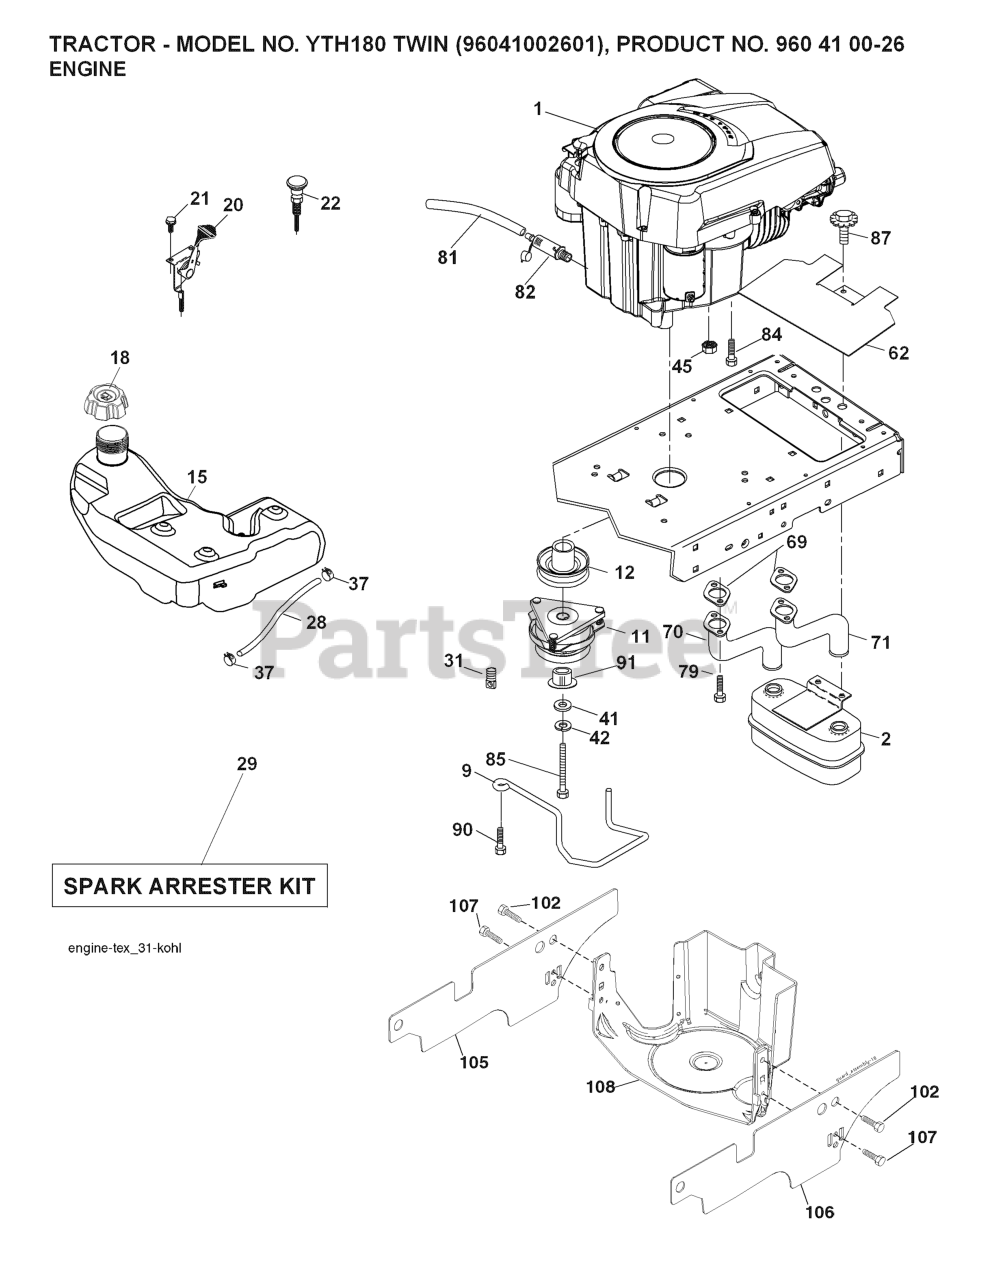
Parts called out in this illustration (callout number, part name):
2	MUFFLER.TWIN.CYL.LOW.TONE
9	KEEPER.BELT.ENGINE.3.25 (3 2)
11	RB.CLUTCH.OGURA.4.4.PD
12	PULLEY.ASM.ENG.OGURA.3
15	TANK.FUEL.4GAL
18	CAP.FUEL.TANK.3"GREY
20	THROTTLE CONTROL
21	SCREW
22	CONTROL.CHOKE.ERGO.PUSH-IN.BLA
28	REPL BY 532 00 85-43
29	KIT.SPARK ARRESTOR 794945 B&S
37	HOSE CLAMP
42	LOCKWASHER
45	NUT
62	RP SHIELD HEAT MUFFLER
69	GASKET.EXHAUST.KOHL.CV18-CV26
70	RP.PIPE-EXHAUST LH
71	RP.PIPE-EXHAUST RH
79	SCREW.SOCKET HD.5/16-1
81	TUBE, DRAIN OIL ASM.
82	PLUG DRAIN OIL EASY
84	SCREW 3/8-16X1
85	BOLT HEX 7/16-20X4-1/4"
87	BOLT.5/16-18UNCX1.W/SEMS.BLK
90	SCREW 3/8-16X1
91	BUSHING.1.375OD
102	SCREW
105	SHIELD.SIDE.LH.3842"TEX FRENCH
106	SHIELD.SIDE.RH.3842"TEX FRENCH
107	SCREW.1/4-20X5/8
